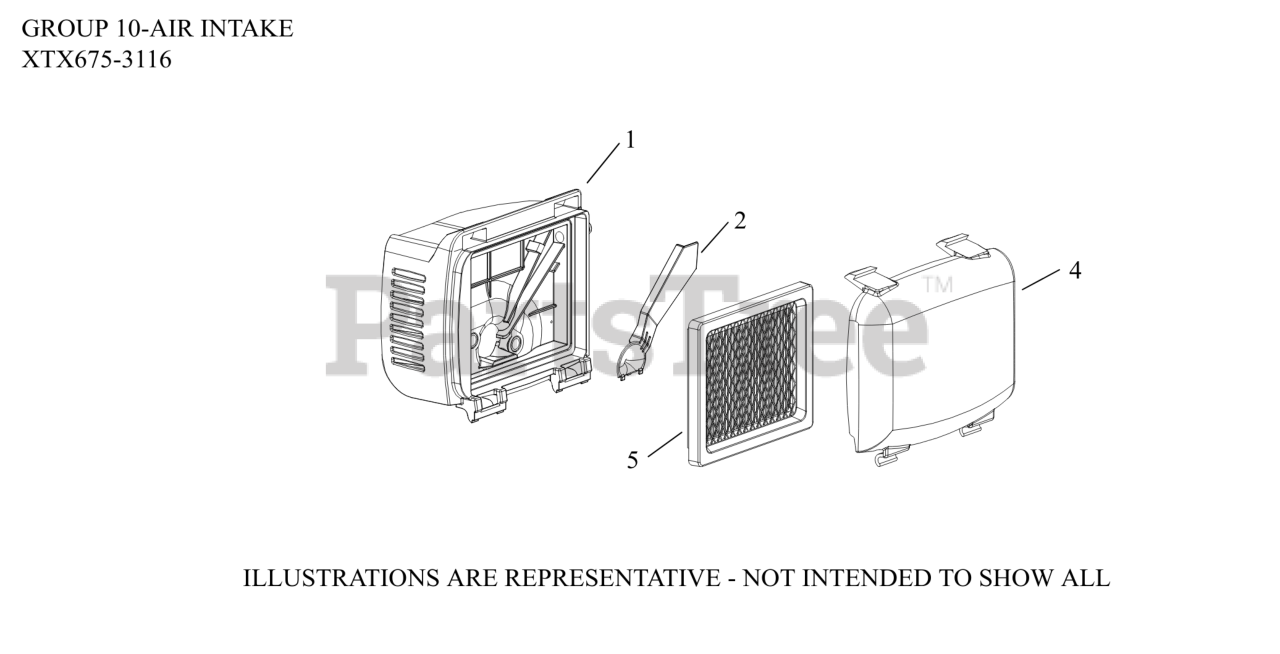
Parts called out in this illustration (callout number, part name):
1	BASE, AIR CLEANER
4	COVER, AIR CLEANER
5	ELEMENT, AIR FILTER
